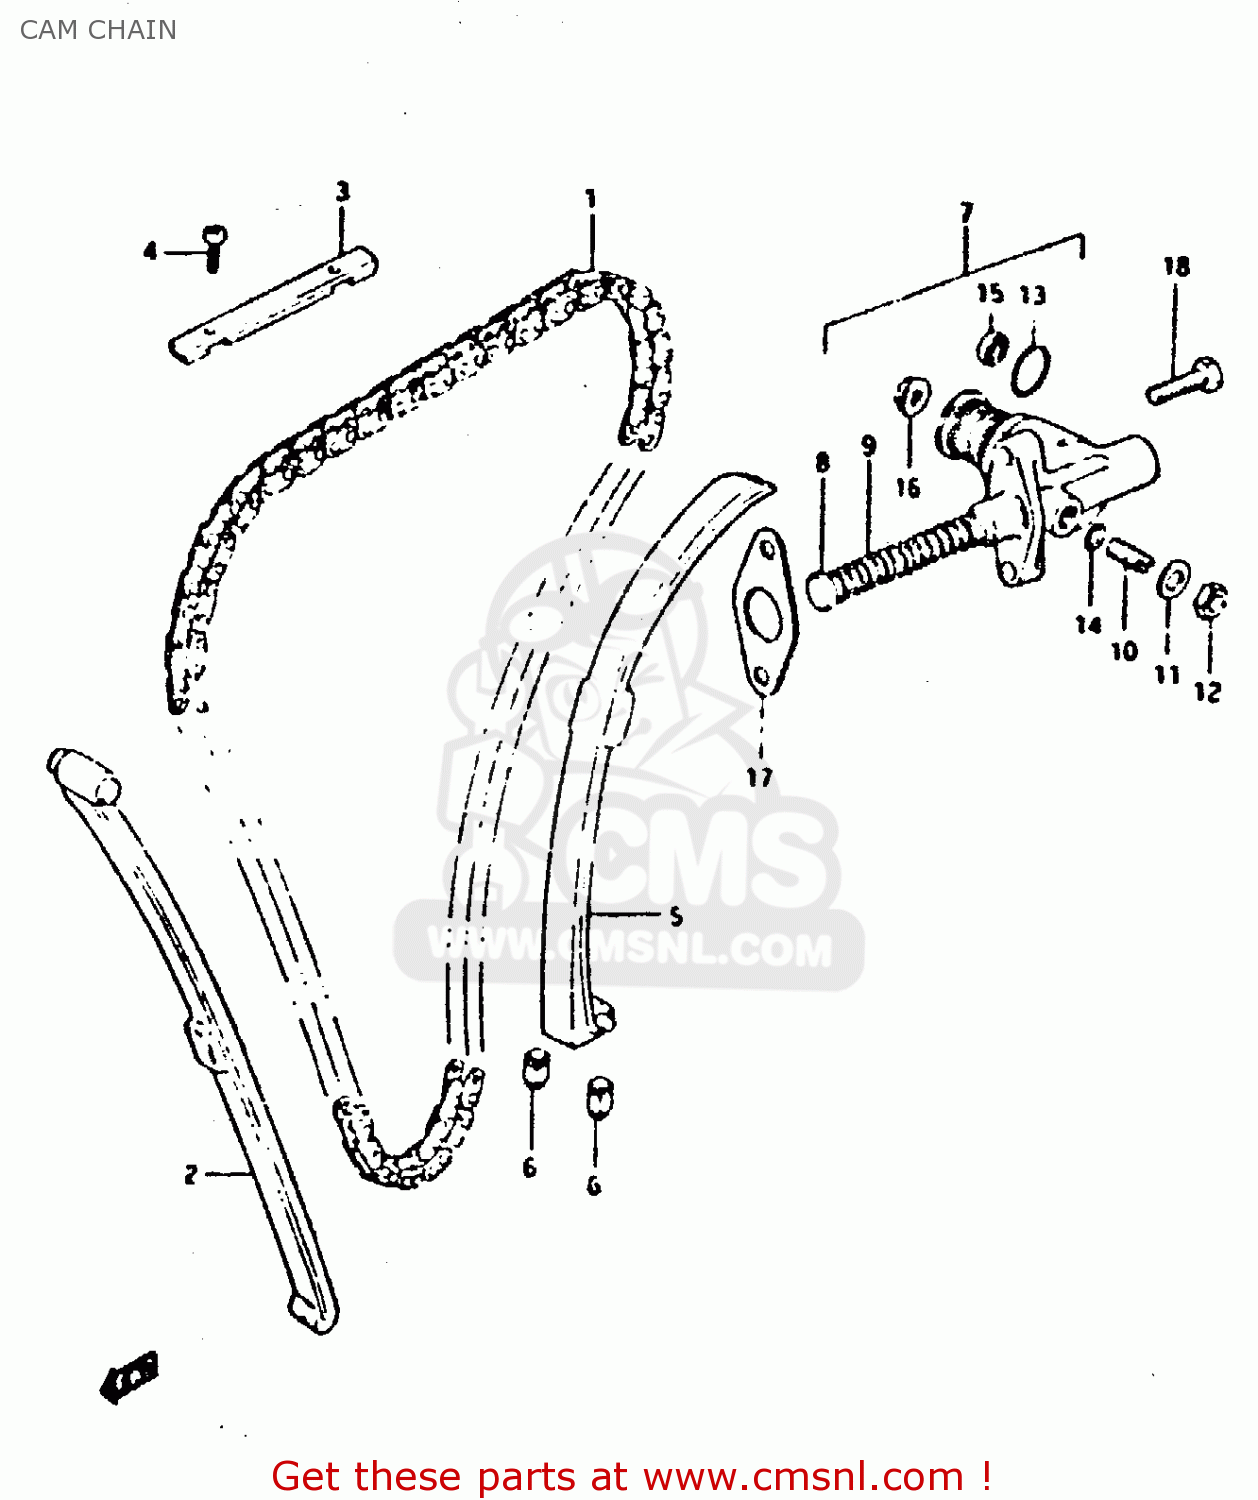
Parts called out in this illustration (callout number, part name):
1	CHAIN,CAMSHAFT DRIVE(120L)
2	GUIDE,CAM CHAIN
3	GUIDE,CAM CHAIN
4	SCREW
5	TENSIONER,CAM CHAIN
6	CUSHION,CAM CHAIN TENSIONER
7	ADJUSTER,CAM CHAIN TENSIONER
8	ROD,PUSH
9	SPRING
10	SCREW
11	WASHER
12	NUT
13	O RING(D:2.4,ID:20.8)
14	O RING(D:1.9,ID:5.7)
15	SEAL,OIL(10X16X4)
16	NUT
17	GASKET,TENSIONER ADJUSTER (MCA)
18	SCREW (6X25)
